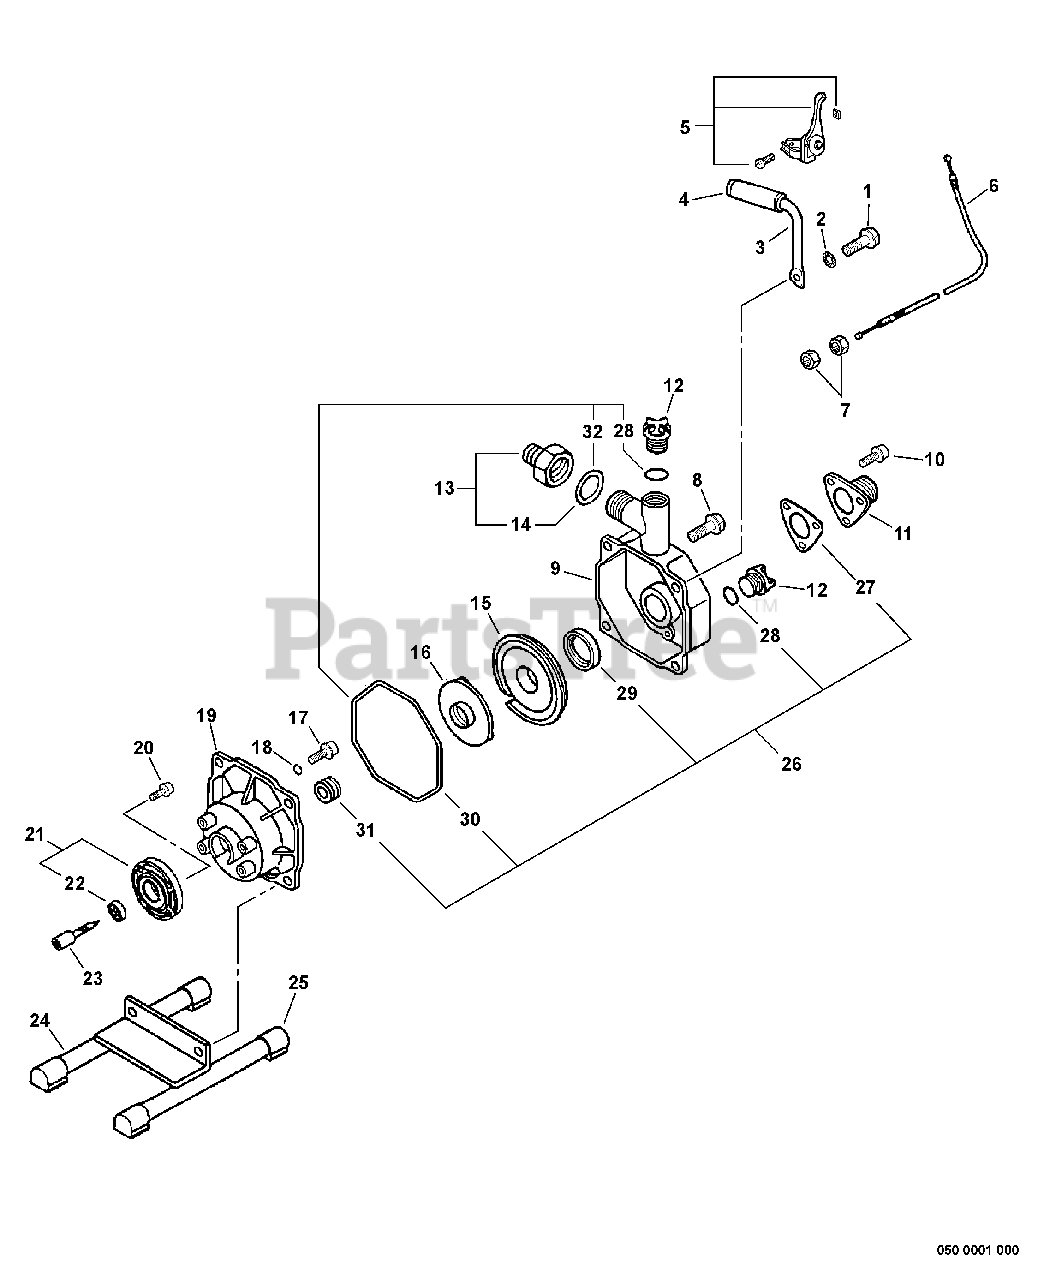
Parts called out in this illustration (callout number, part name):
1	BOLT - 8×35 -- TAPPING
4	GRIP, REAR HANDLE
5	CONTROL, THROTTLE
6	CABLE, THROTTLE
8	BOLT - 8×25 -- TAPPING
9	CASE, PUMP
10	BOLT - 6×20
11	PORT, SUCTION
12	PLUG
13	NIPPLE - 1×3/4"
16	IMPELLER
17	BOLT 5×25
19	CASE, PUMP
20	BOLT 5×25
21	PUMP ADAPTOR ASSY
22	BEARING, BALL 6201
23	SHAFT, PUMP
24	FRAME, PUMP
26	PUMP REBUILD KIT
27	VALVE, CHECK
28	O-RING P-24
29	GASKET, PUMP
31	SEAL, MECHANICAL
